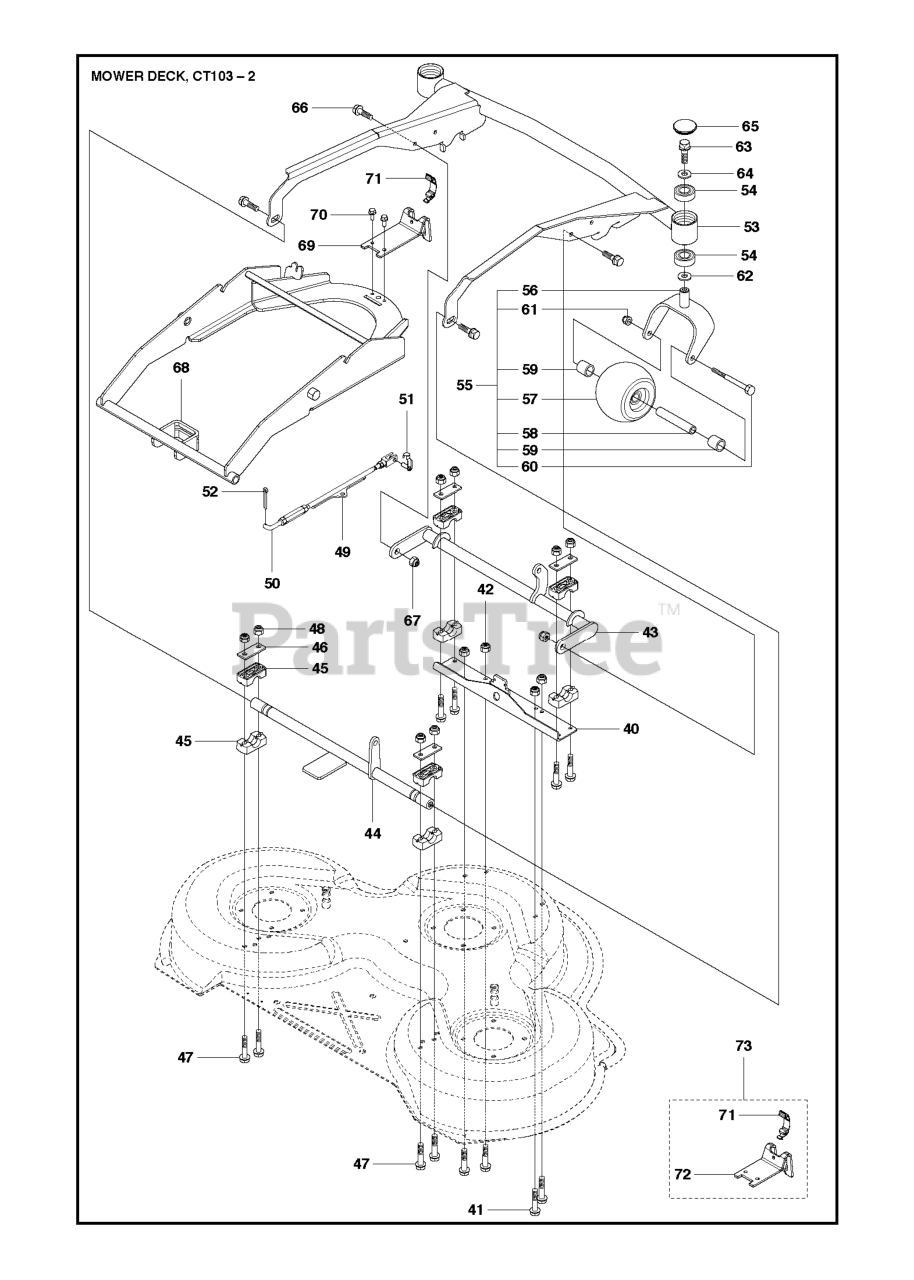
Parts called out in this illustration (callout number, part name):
2	RP BOLT 5/16-18 X3/4 ZN/YEL GR
5	RETAINER-SPRNG RB
6	BAR.SWAY.92.CRD
8	BOLT.3/8-24X1.25 GR8
9	LOCKWASHER
10	WASHER.BLADE
13	SHAFT ASM VENT
14	HOUSING.MANDREL.VENTED (MACHD)
17	BOLT.3/8-14X1.25
19	BOLT SHD 5/16-18
20	BOLT.3/8-24X1.25GR8. LHTHRD
21	LOCKNUT
26	SUPPORT
30	SCREW, WASHER HEAD
31	WASHER.SPACER.MANDREL
32	PULLEY MANDREL
33	NUT.FLANGE.LOCK.TOP
36	PULLEY.IDLER.4.25
41	NUT LOCK FLG 3/8-16 UNC
45	COVER.MANDREL.RH.CRD
46	SCREW.1/4-20X5/8
55	ARM.IDLER.92 CRD.2006
56	SPACER.RETAINER.MOWER
61	SPRING
67	KNOB T (3/8 HOLE)
68	BELT.DRIVE.92CM.CRD.2006
69	SHAFT.ASM.W/LWR.BRG.RH.THREAD
84	KEEPER, BELT IDLER
116	BOLT.SHOULDER.3/8-16X3-5/8.
117	RP WHEEL. GUAGE RALLY
119	WASHER
124	BOLT.3/8-16X1.50
130	BOLT.CARR.SQNK.5/16-18UNC.X3/4
131	CHUTE BAGGER
158	SCREW
185	HEAD ASM. CABLE CLUTCH
254	SCREW 3/8-16X1
296	BOLT
297	NUT CENTERLOCK
